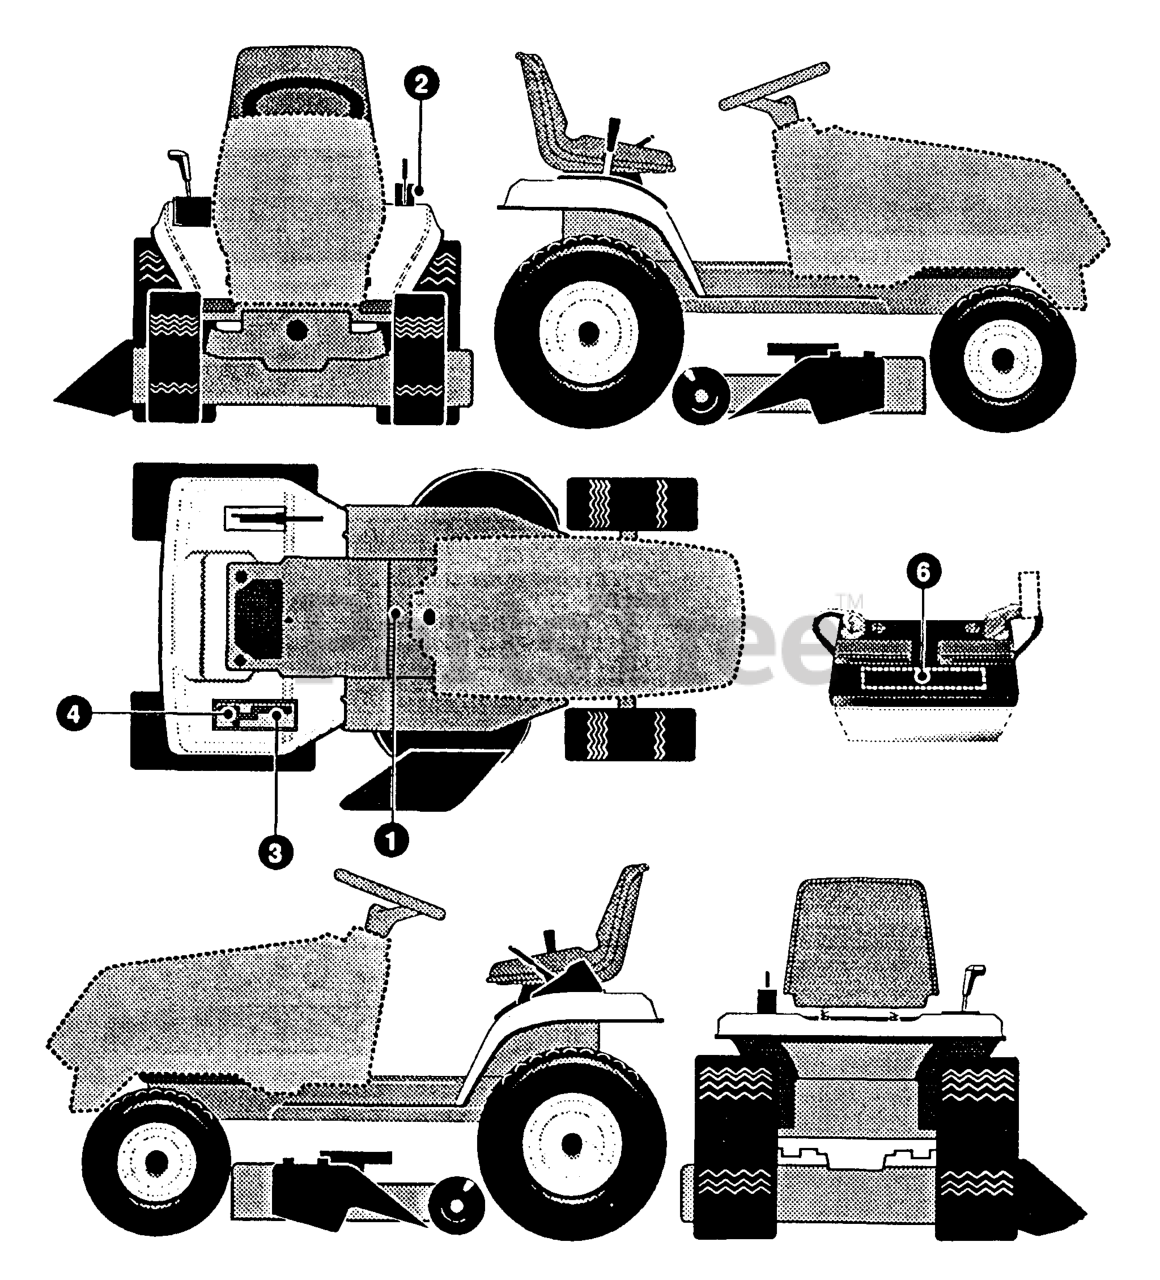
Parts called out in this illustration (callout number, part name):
1	CAUTION CONSOLE TOP
2	HEIGHT ADJUST
3	SHIFTER POSITION
4	SHIFT REV
6	BATTERY- FRE/ENG
